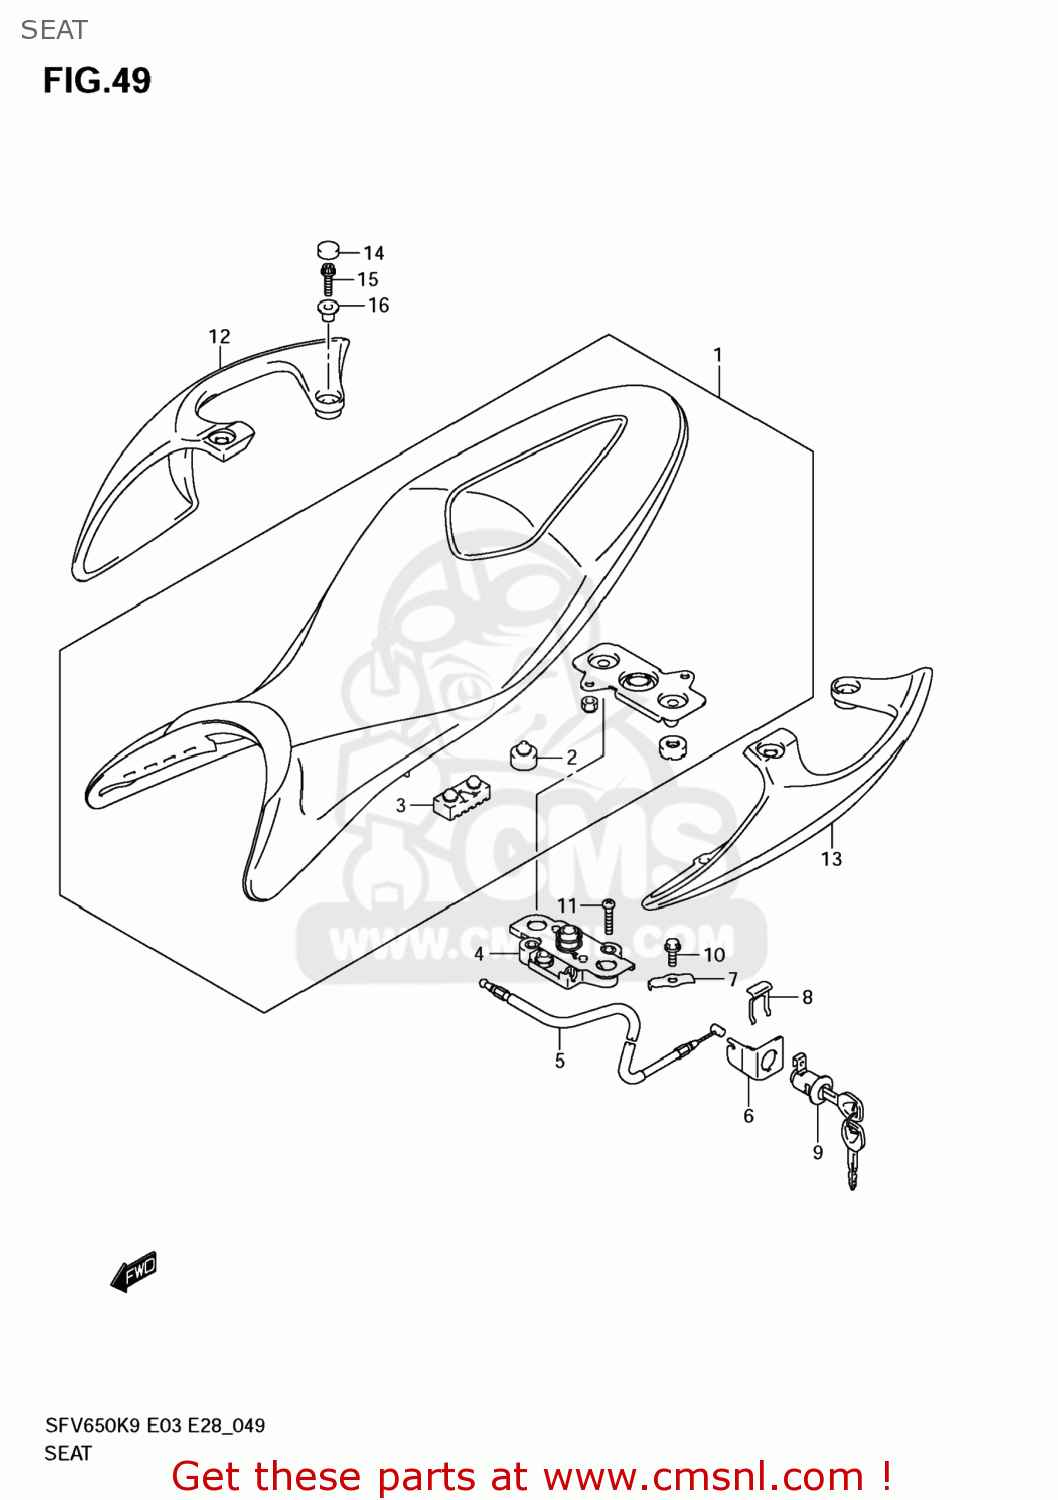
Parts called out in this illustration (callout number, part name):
1	SEAT ASSY
2	CUSHION
3	CUSHION
4	BRACKET,STRIKER SUPPORT
5	CABLE COMP,SEA
6	GUIDE,SEAT LOCK CABLE
7	GUIDE,SEAT LOCK CABLE
8	PLATE,SEAT LOCK ASSY
9	LOCK SET,SEAT
10	BOLT
11	SCREW
12	HANDLE,PILLION RIDER,R
13	HANDLE,PILLION RIDER,L
14	CAP
15	BOLT(8X25)
16	WASHER
